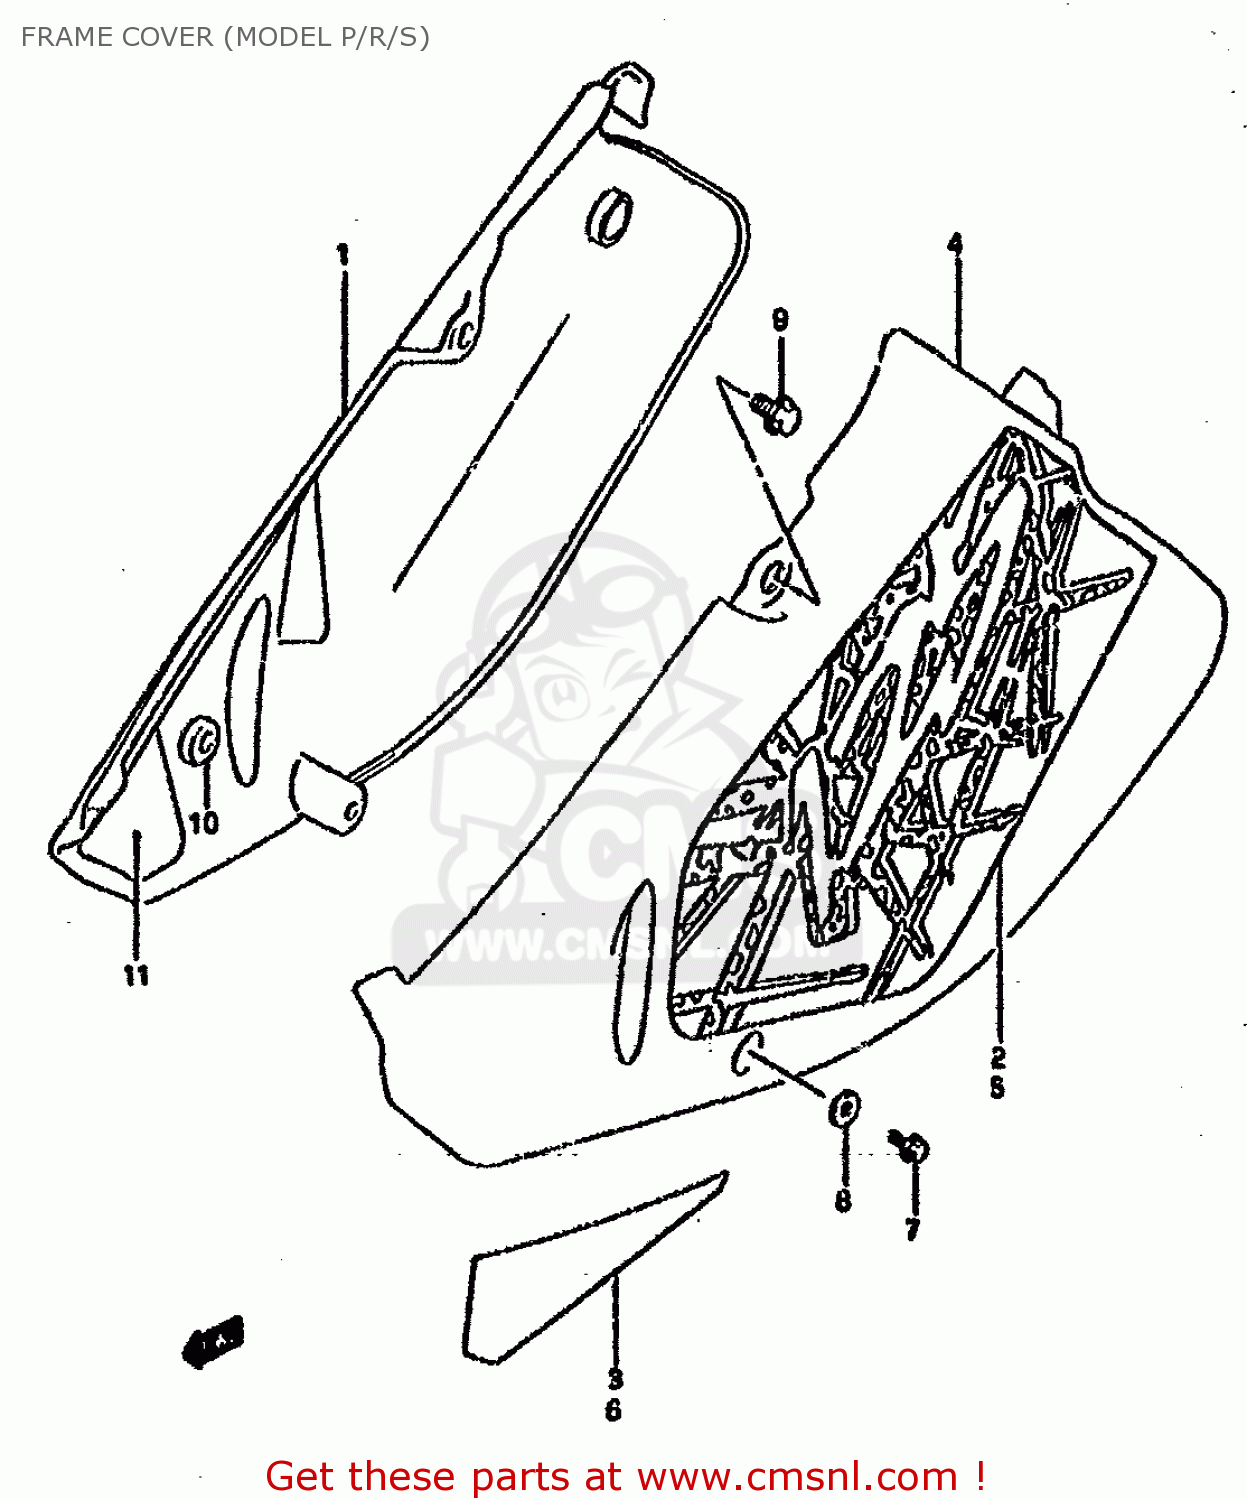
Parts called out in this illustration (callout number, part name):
1	COVER,FRAME,RIGHT
2	EMBLEM,FRAME COVER,RIGHT
3	EMBLEM,FRAME COVER,RIGHT
4	COVER,FRAME,LEFT
5	EMBLEM,FRAME COVER,LEFT
6	EMBLEM,FRAME COVER,LEFT
7	BOLT
8	WASHER
9	BOLT
10	CUSHION
11	SHIELD,FRAME COVER,RIGHT H
